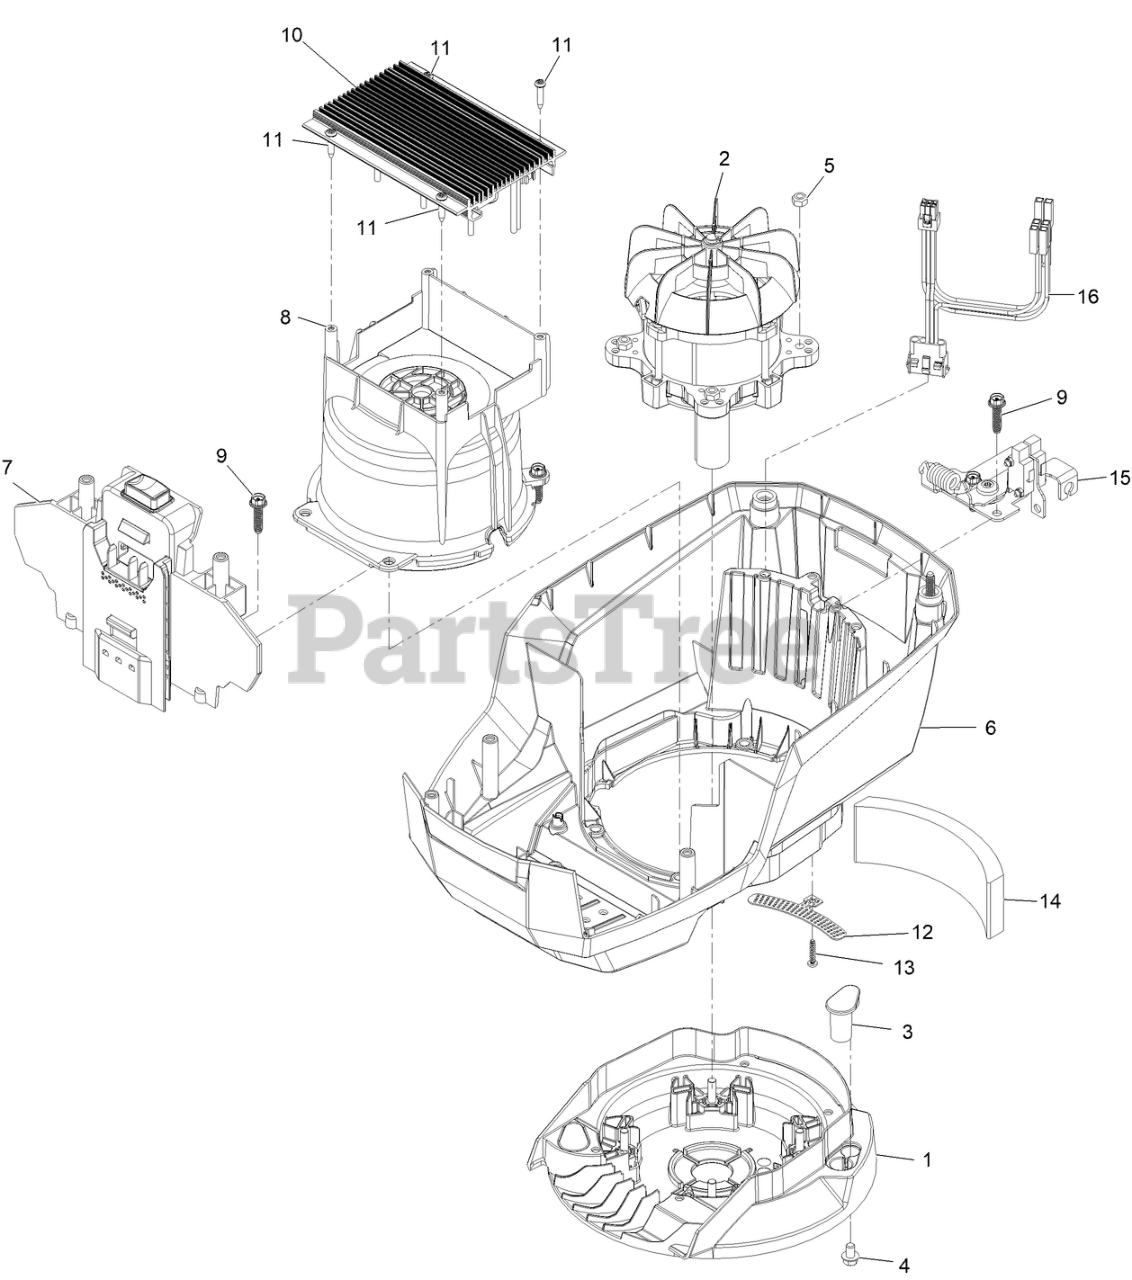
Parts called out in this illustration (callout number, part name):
1	BASE-MOUNT, MOTOR
2	MOTOR-2KW
3	INSERT-MOUNT, MOTOR
5	NUT-LOCK
6	SHROUD-LOWER
7	BATTERY RECIEVER ASM
8	SHROUD-MOTOR
9	SCREW-FLANGE, PLASTIC
10	CONTROLLER-MOTOR
12	BRACKET-FOAM
13	SCREW-PLASTIC, PPH
15	BAIL SWITCH ASM
16	HARNESS-WIRE
